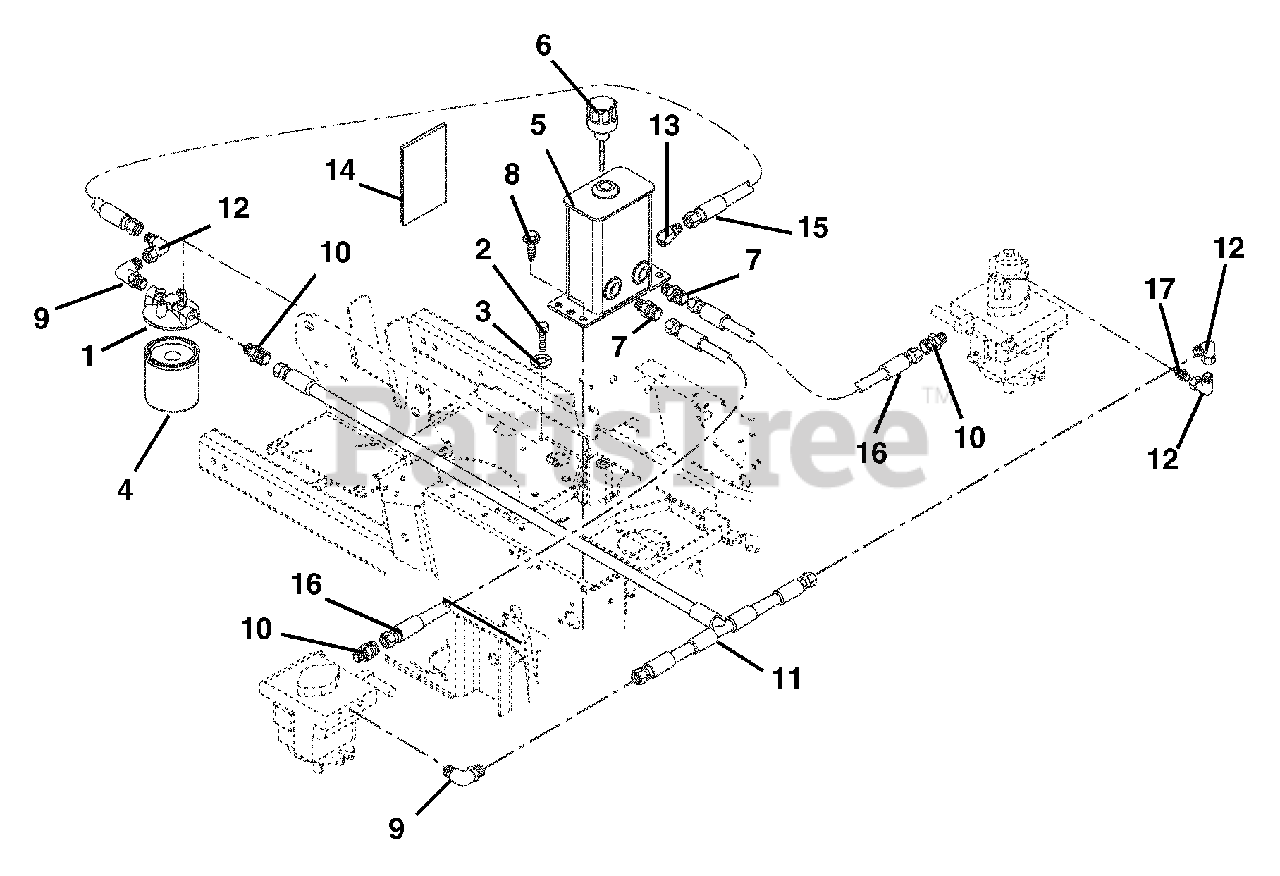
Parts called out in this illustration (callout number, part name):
1	HEAD, FILTER
2	@BLT-HEX .25-20X.50 GR5 YWZC
3	@WSHR-LK .25X.062 REG YWZC
4	ELEMENT, FILTER BE-40-0
5	WMT, HYDRAULIC TANK
6	BREATHER, DIPSTICK
7	ADPT - STRAIGHT 6-8F50X
8	@SCR-TAP .38-16X.50 HWH TR YWZ
9	ADPT 2503-6-6
10	ADPT-PIPE (0503-6-6)
11	HOSE, TEE ASSEMBLY 3/8"
12	ADPT 3903-6-6
13	FTG HYD 45DEG M6J-M8O
14	SHEILD, HEAT 5.50X4.50
15	HOSE, HYD .38-9-0K F6J0-F6J0
16	HOSE, HYD .38-3-0K F6J0-F6J9
17	ADP 0503-4-6
